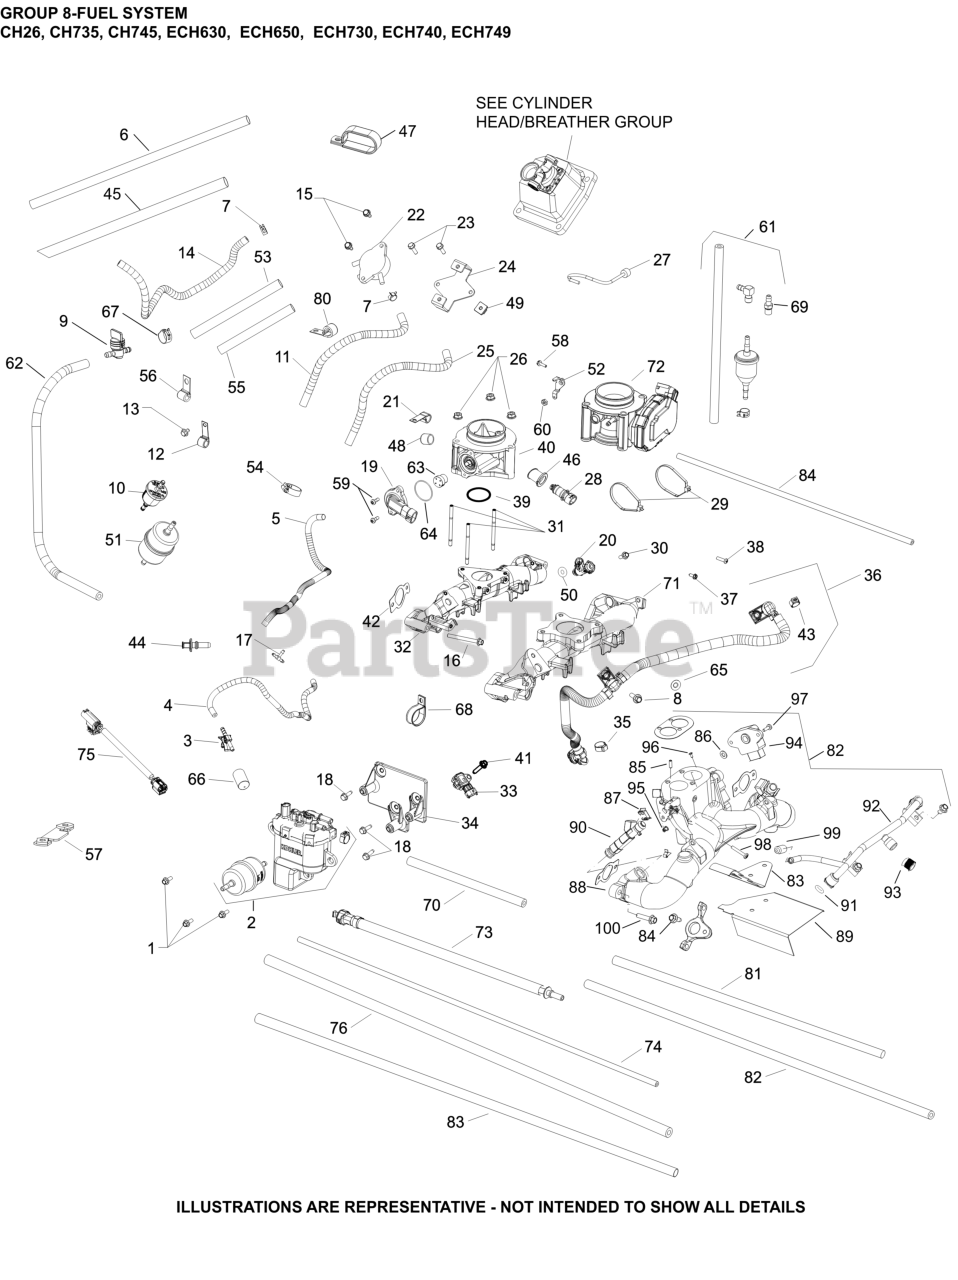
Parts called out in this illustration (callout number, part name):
1	SCREW, FLG M6X1.0X16
2	KIT, FUEL PUMP MODULE
4	HOSE, EVAPORATIVE (15.0)
5	SLEEVE, ANTI-ABRASION
7	CLAMP, HOSE (KM)-USE 25 237 31-S
8	SCREW, FLG M6x1.0x20
10	FILTER, FUEL
11	HOSE,LW PERM.FUEL 24.00"-USE 25 111 81-S
16	SCREW, FLG M6X1.0X60
17	TEE CONNECTOR
18	SCREW, THREAD FORMING
19	SENSOR, THROTTLE POSITION
20	INJECTOR, FUEL
21	CLIP, CABLE
31	STUD,M6X1.0X84
32	KIT, MANIFOLD
33	SENSOR, T-MAP
34	BAFFLE, FUEL MODULE
35	CLAMP, HOSE
36	FUEL HOSE ASSEMBLY,ECH680-ECH749
39	O-RING, THROTTLE BODY
40	BODY, THROTTLE ASM W/ PIN (30)
42	KIT, INTAKE MANIFOLD GASKET
43	CLAMP, OETIKER
48	CAP, MASKING
50	KIT, FUEL INJECTOR O-RING
55	SLEEVE, ANTI ABRASION-USE 25 431 12-S
63	MAGNET ASSEMBLY, TPS
64	O-RING, TPS SENSOR
65	CLIP, RETAINER
68	CLAMP, INSULATED
80	CLIP, CABLE (KM)
